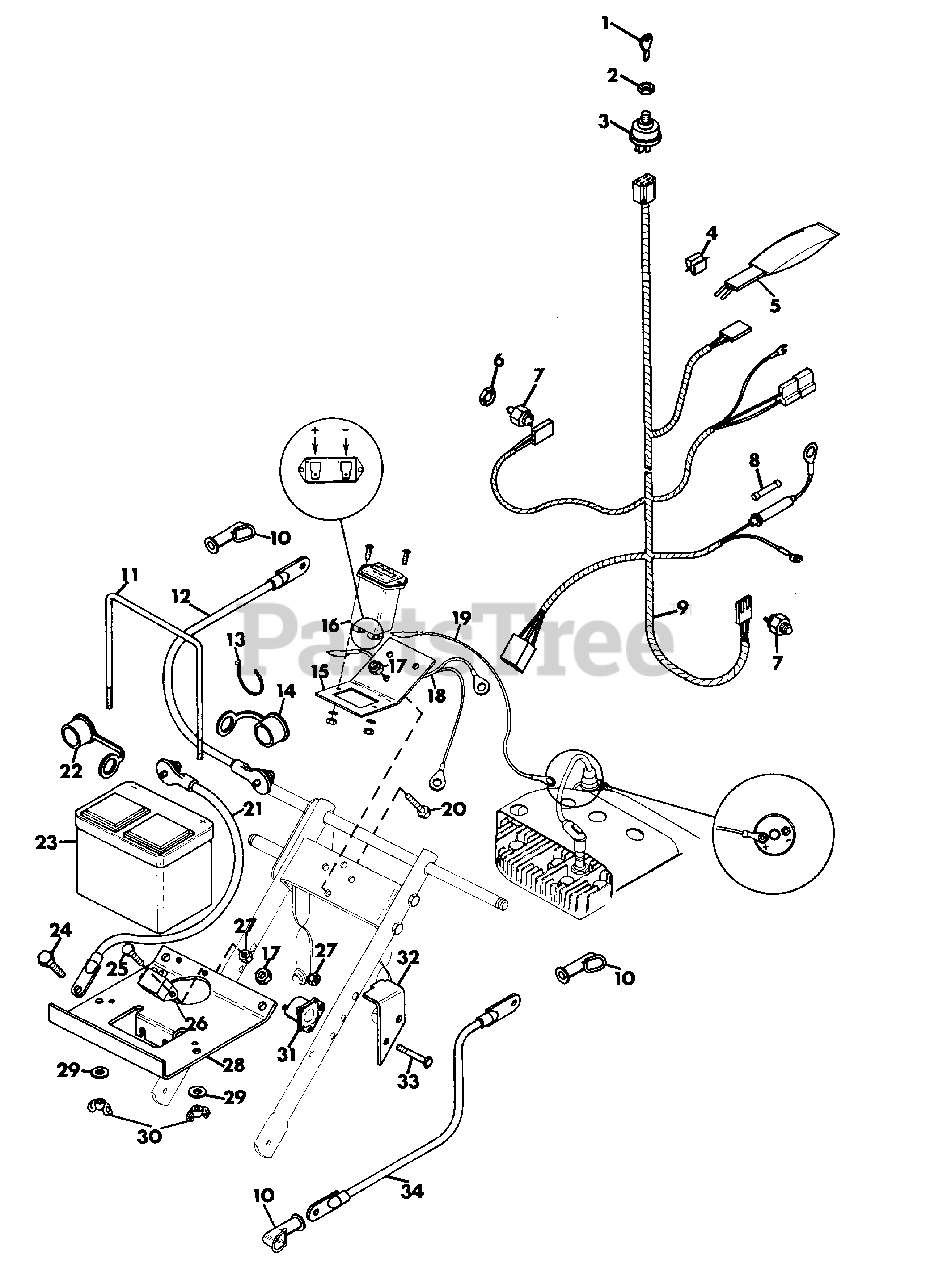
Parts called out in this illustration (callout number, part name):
1	KEY, IGNITION
2	NUT, JAM 9/16-24
3	SWITCH, IGNITION
4	CLIP, WIRE
5	SWITCH, SEAT
6	NUT, STAMPED
7	SWITCH, INTERLOCK
8	FUSE, 30 AMP
9	HARNESS, WIRING
10	BOOT, BATTERY CABLE
11	ROD, BATTERY
12	CABLE, POSITIVE BATTERY
13	TIE, CABLE
14	COVER, BATTERY POS.
15	BRACKET, HOURMETER
16	HOURMETER
17	NUT, LOCK 3/8-16
18	WIRE, GROUND PRO MASTER-50
19	WIRE, HOURMETER
20	BOLT, HEX 3/8-16X.875
21	CABLE, NEGATIVE BATTERY
22	COVER, BATTERY NEG.
23	BATTERY, DELCO MAINTENANCE-FREE #101 -REPLACEMENT BATTERY #83-50
24	BOLT, HEX 3/8-16X2.25
25	BOLT, HEX 1/4-20X1.00
26	REGULATOR, RECTIFIER
27	NUT, LOCK 1/4-20
28	BOX, BATTERY
29	WASHER, FLAT .281X.625X.065
30	NUT, WING 1/4-20
31	SWITCH, MAG
32	BRACKET, PTO
33	BOLT, HEX 1/4-20X2.00
34	CABLE
